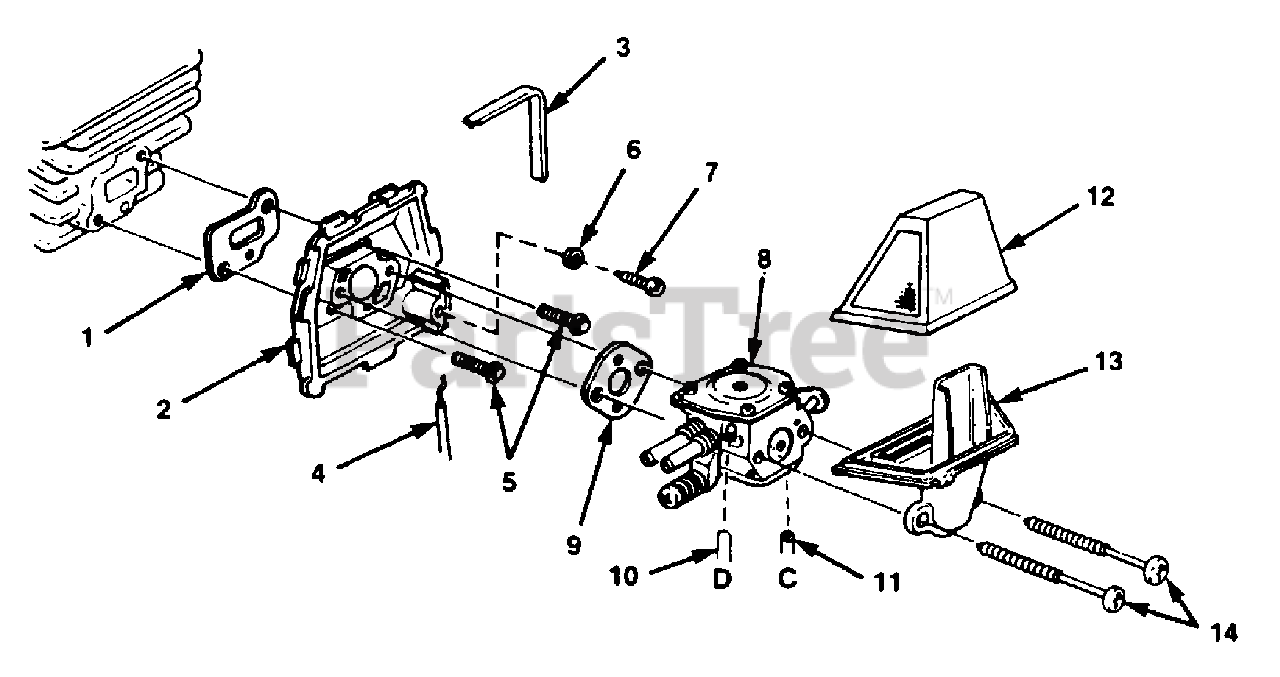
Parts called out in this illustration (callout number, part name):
1	GASKET- Carburetor spacer
2	SPACER- Carburetor
3	FOAM- Adhesive
4	CABLE- Throttle
5	SCREW- Carburetor spacer
7	SCREW (6-19 x 1/2")
8	CARBURETOR- Walbro (HDA-99)
9	GASKET
10	TUBING- Rubber
11	TUBING- Rubber
12	ELEMENT-Air filter
13	BODY- Air filter
14	SCREW (8-16 x 2")
